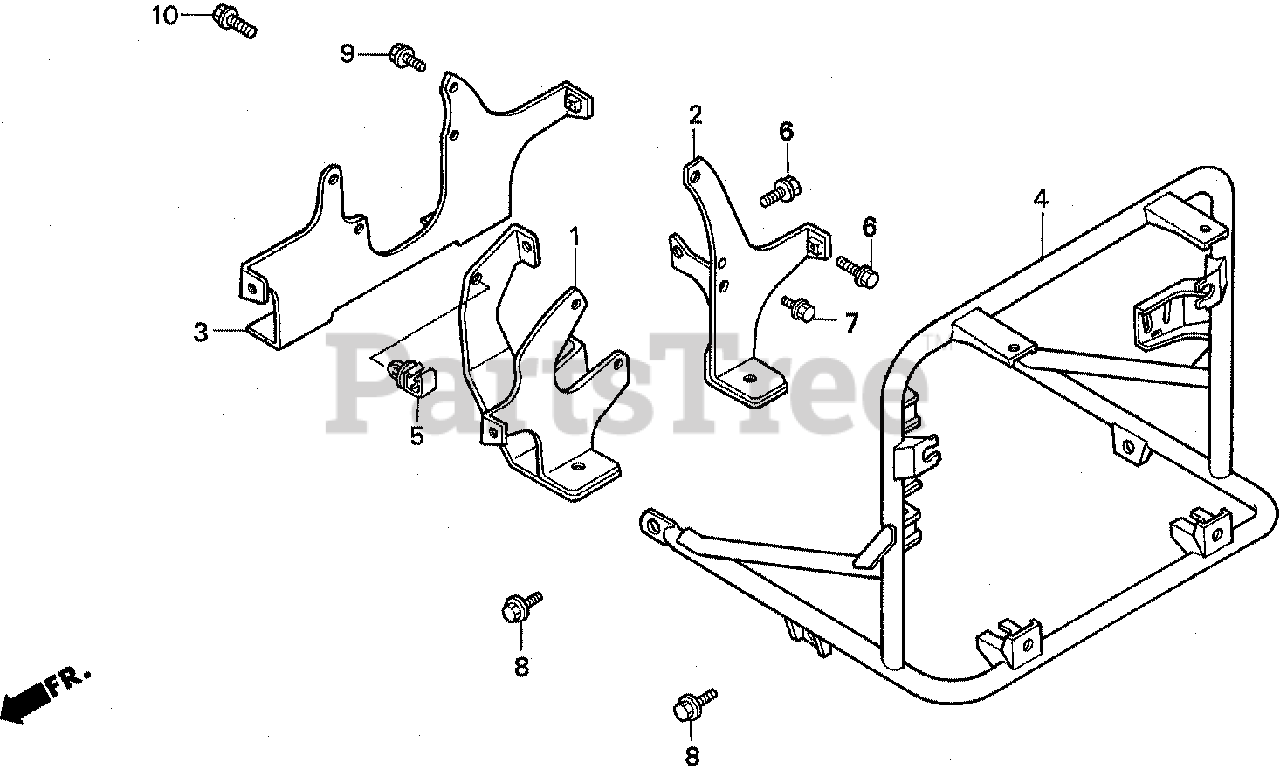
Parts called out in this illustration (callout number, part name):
1	STAY, R. FR. ENGINE MOUNTING
2	STAY, L. FR. ENGINE MOUNTING
3	STAY, R. RR. ENGINE MOUNTING
4	FRAME
5	CLIP, WIRE HARNESS
6	BOLT, FLANGE (8X20)
7	BOLT, FLANGE (6X10)
8	BOLT, FLANGE (8X16)
9	BOLT, FLANGE (8X20)
10	BOLT, FLANGE (8X25)
